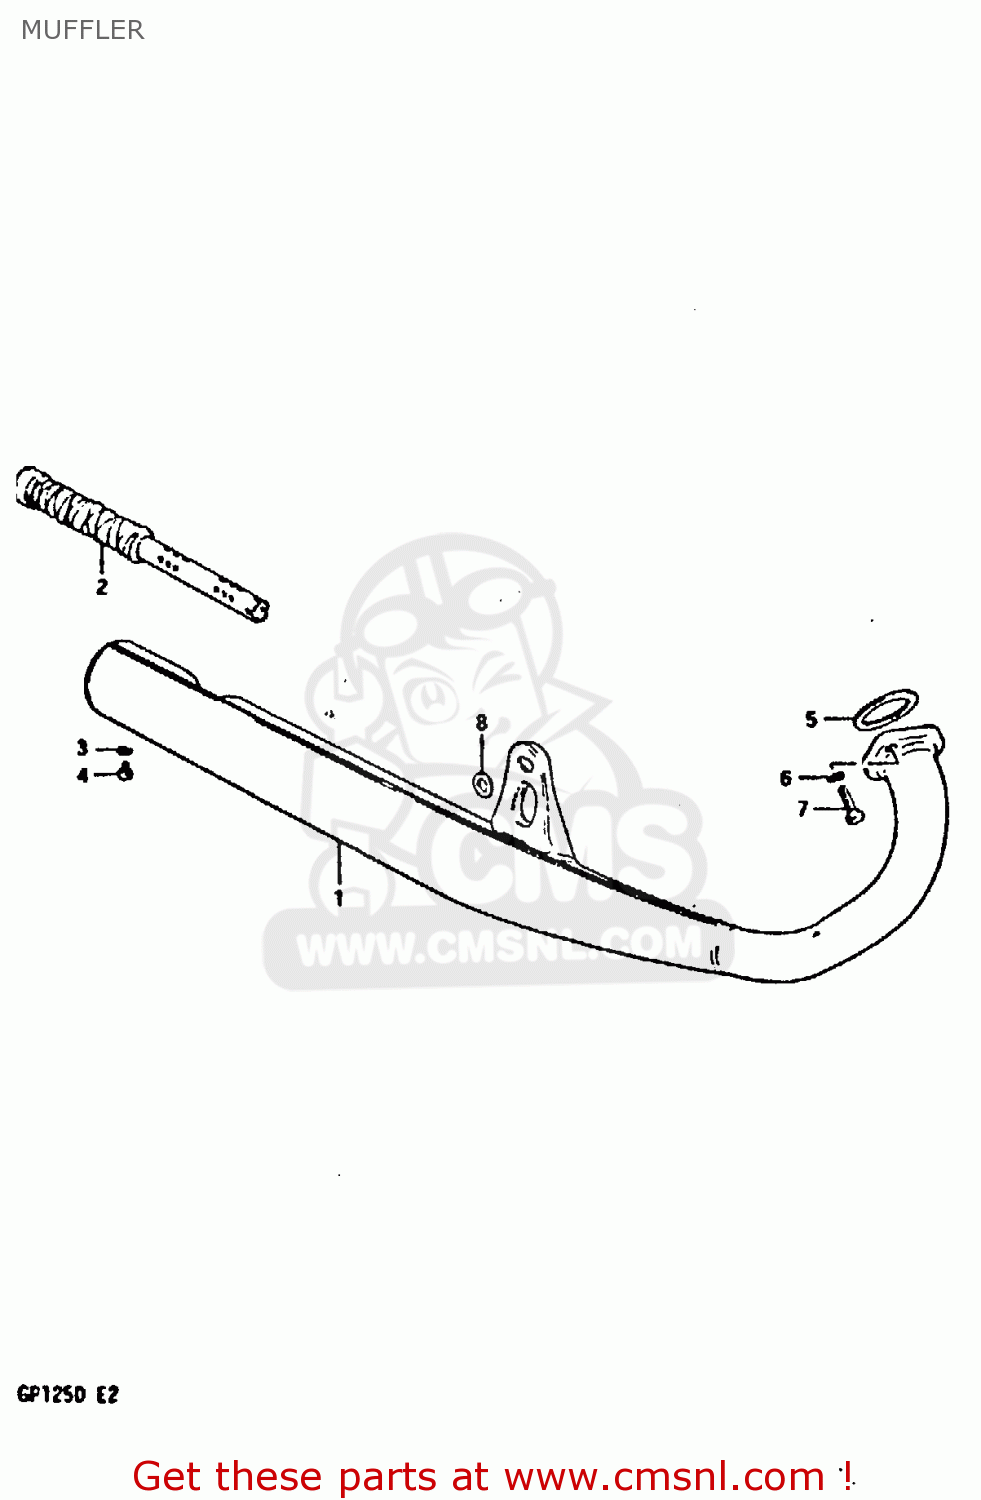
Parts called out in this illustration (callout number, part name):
1	MUFFLER ASSY
2	PIPE, BAFFLE
3	LOCK WASHER
4	BOLT(5X8)
5	GASKET,EXHAUST PIPE (NAS)
6	LOCK WASHER
7	BOLT
8	WASHER (12.5X24X3.2)
